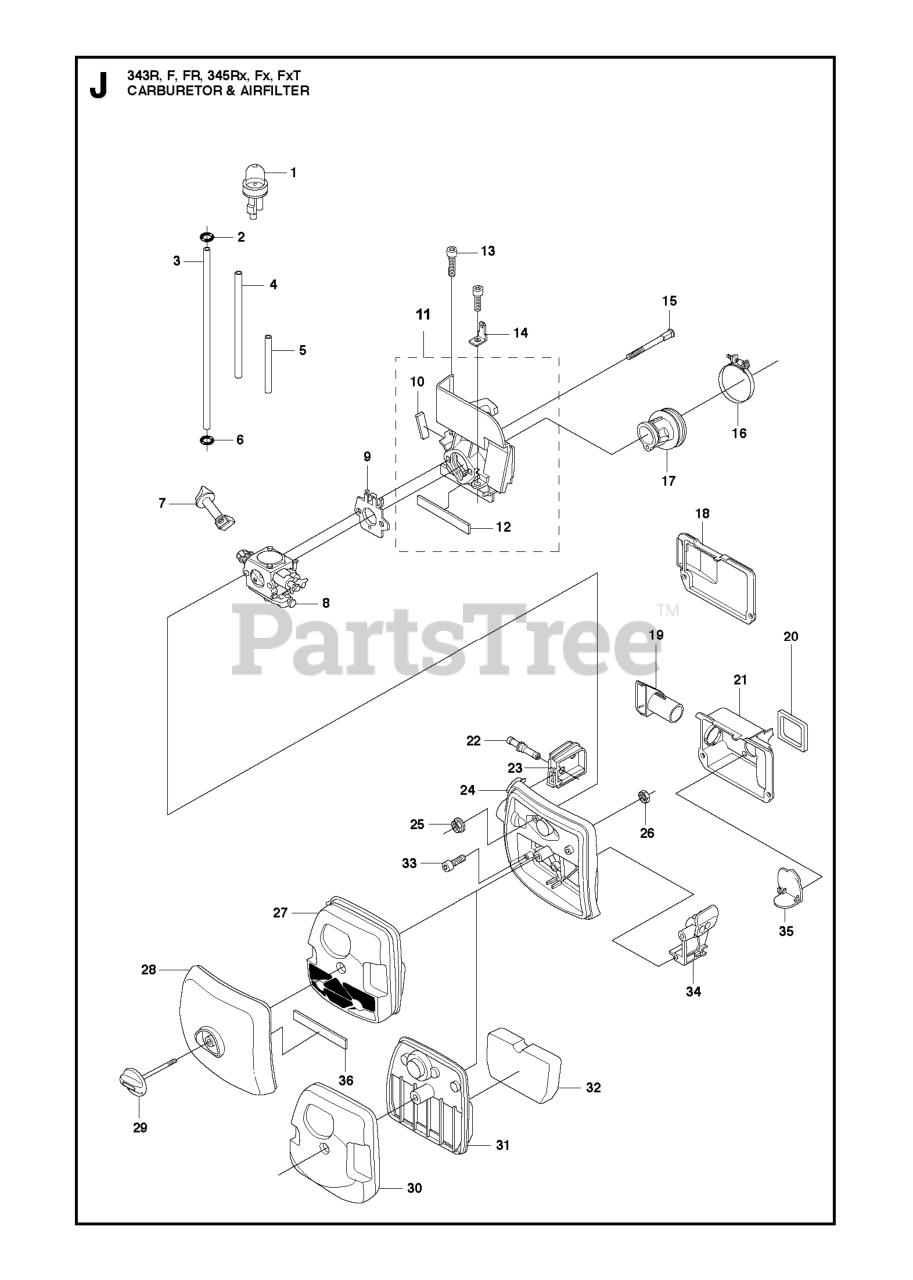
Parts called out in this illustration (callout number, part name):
1	AIR PURGE BUBBLE
3	FUEL HOSE
4	HOSE.FUEL L=102
5	NOSE
7	CHOKE CONTROL
8	CARBURETOR
9	SPACER WASHER
16	CLAMP
18	COVER
19	AIR CONDUCTOR
20	SEAL
21	AIR CAN
24	FILTER HOLDER
26	NUT M6M M5
27	AIR FILTER
28	RP FILTER COVER COMP
29	HANDLE AIR FILTER COVER
30	COVER
31	BASE
32	AIR FILTER
34	SCREW DRIVER GUIDE
35	COVER
